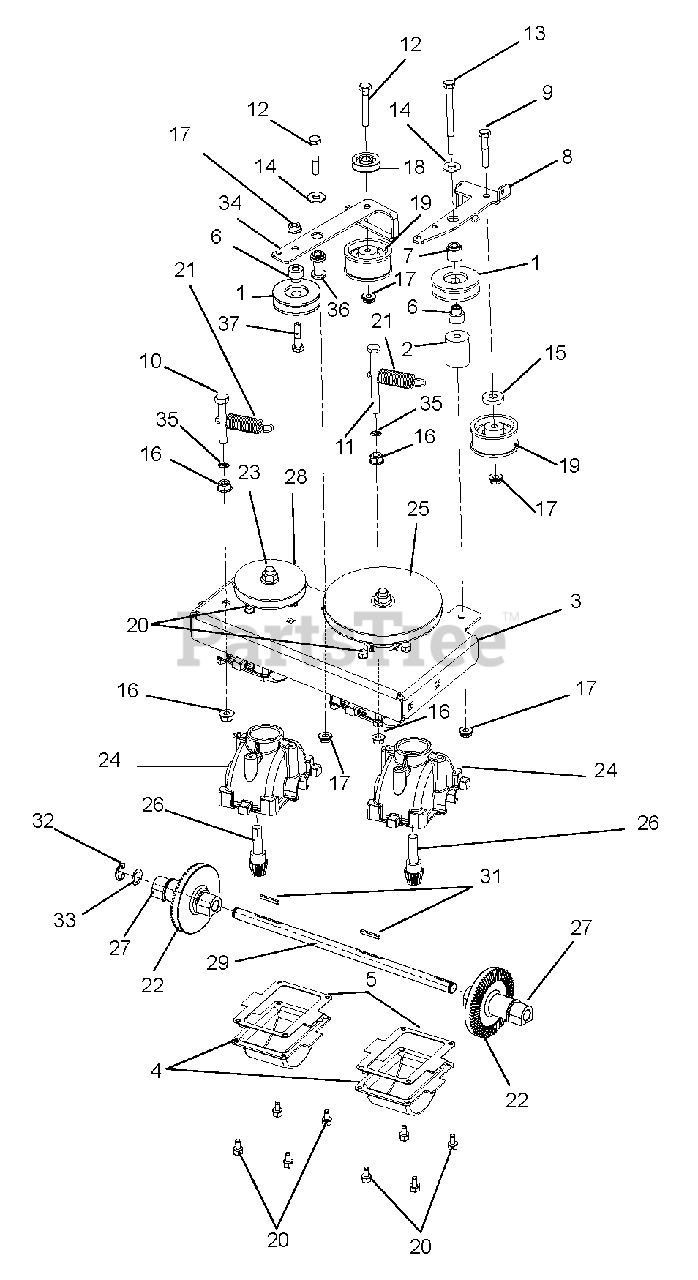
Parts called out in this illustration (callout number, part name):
1	Idler, 3L Front Side .38 x 1.875
2	Spacer, Reverse Idler
3	Plate, Transmission Mount
4	Sump, Gearbox
5	Gasket, Transmission
6	Spacer, Idler Pulley
7	Spacer .390 x .75 x .189
8	Bracket, Transmission Idler Arm
9	Bolt, Hex .25-20 x 1.50
10	Bolt, Hex .31-18 x 2.50 Grade 5
11	Bolt, Hex .31-18 x 3.50 Grade 5
12	Bolt, Hex .25-20 x 1.75
13	Bolt, Hex .25-20 x 3.25
14	Washer, Flat Steel .312 x .734 x .065
15	Washer, Flat Steel .38 x .87 x .179
16	Nut, Spin Lock Flange .312-18
17	Nut, Locking Top Flange .25-20
18	Pulley, Cable
19	Pulley, Idler .25 x 1.87 x .97
20	Screw, Tapping 10-24 x .375 Pre-Coat
21	Spring, Tension .063 x .625 x 2.50
22	Gear, Bevel
23	Nut, Top-Locking Flange .38-16
24	Housing, WAW Gearbox
25	Pulley, Reverse Input
26	Pinion, Gearbox Input
27	Bushing, Transmission Output Shaft
28	Pulley, Transmission Input
29	Shaft, Transmission Output
30	Kit, WAW Transmission Shaft (includes 30, 32, 33 and 34)
31	Key, 1/8 x 1/8 x 1.0
32	Ring, Retaining – External .500 x .042
33	Washer, .500 x .750 x .020 Thrust
34	Arm, Double Acting Idler
35	Nut, Push .312
36	Pivot, Idler
37	Bolt, Hex .25-20 x 1.25 Grade 5
